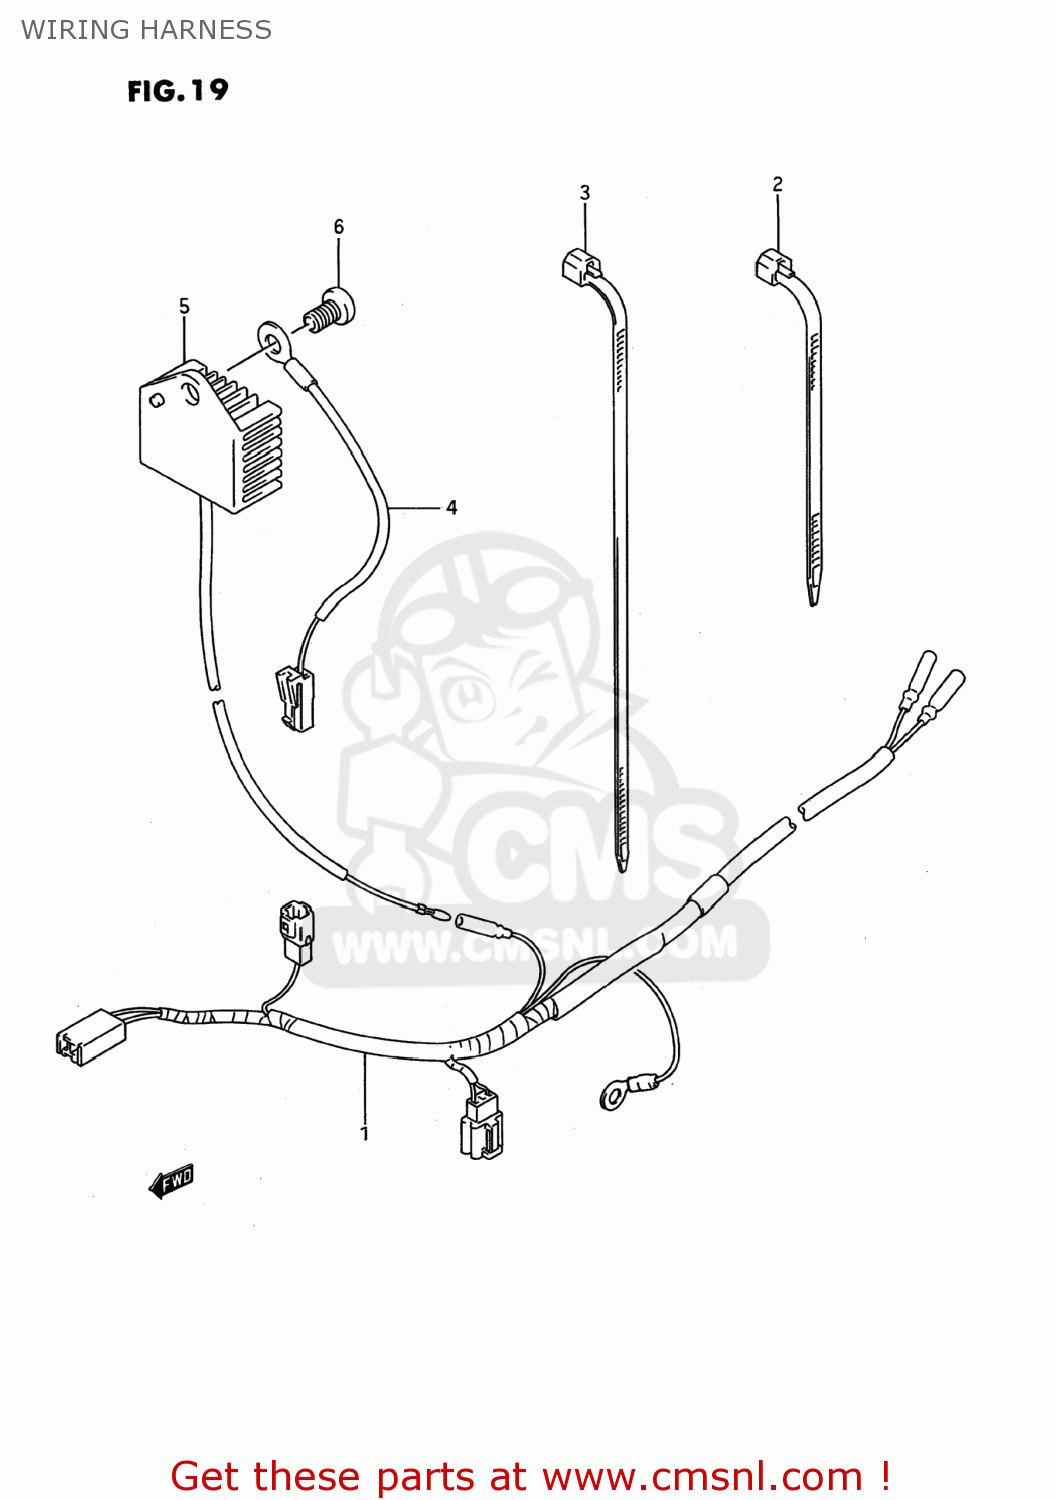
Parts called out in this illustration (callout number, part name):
1	HARNESS,WIRING
2	CLAMP(L:95)
3	CLAMP(L:235)
4	WIRE,REGULATOR EARTH LEAD
5	REGULATOR ASSY
6	SCREW
